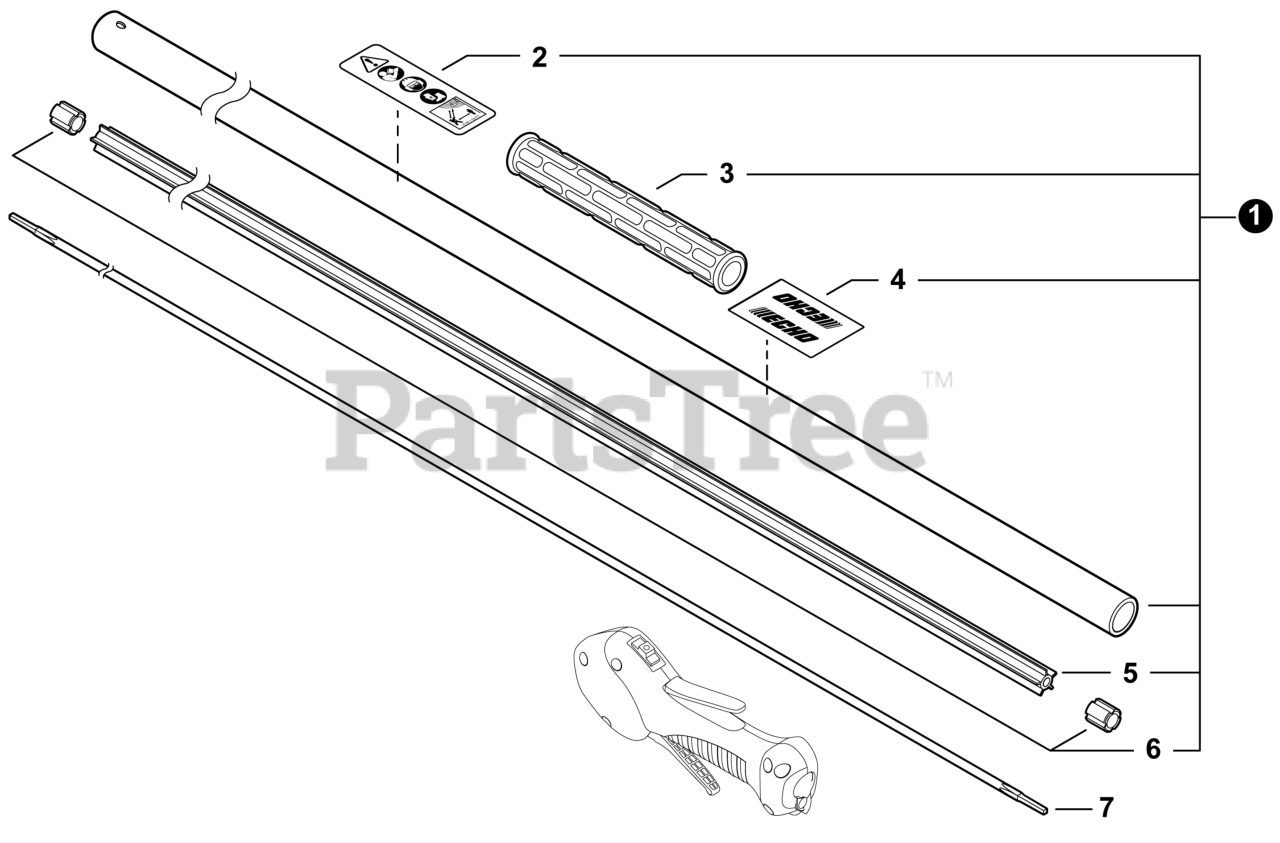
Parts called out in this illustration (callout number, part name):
1	MAIN PIPE ASSY
2	LABEL - CAUTION
3	GRIP, FRONT
4	LABEL - HANDLE LOCATION
5	LINER - FLEXIBLE
7	DRIVESHAFT - FLEXIBLE
